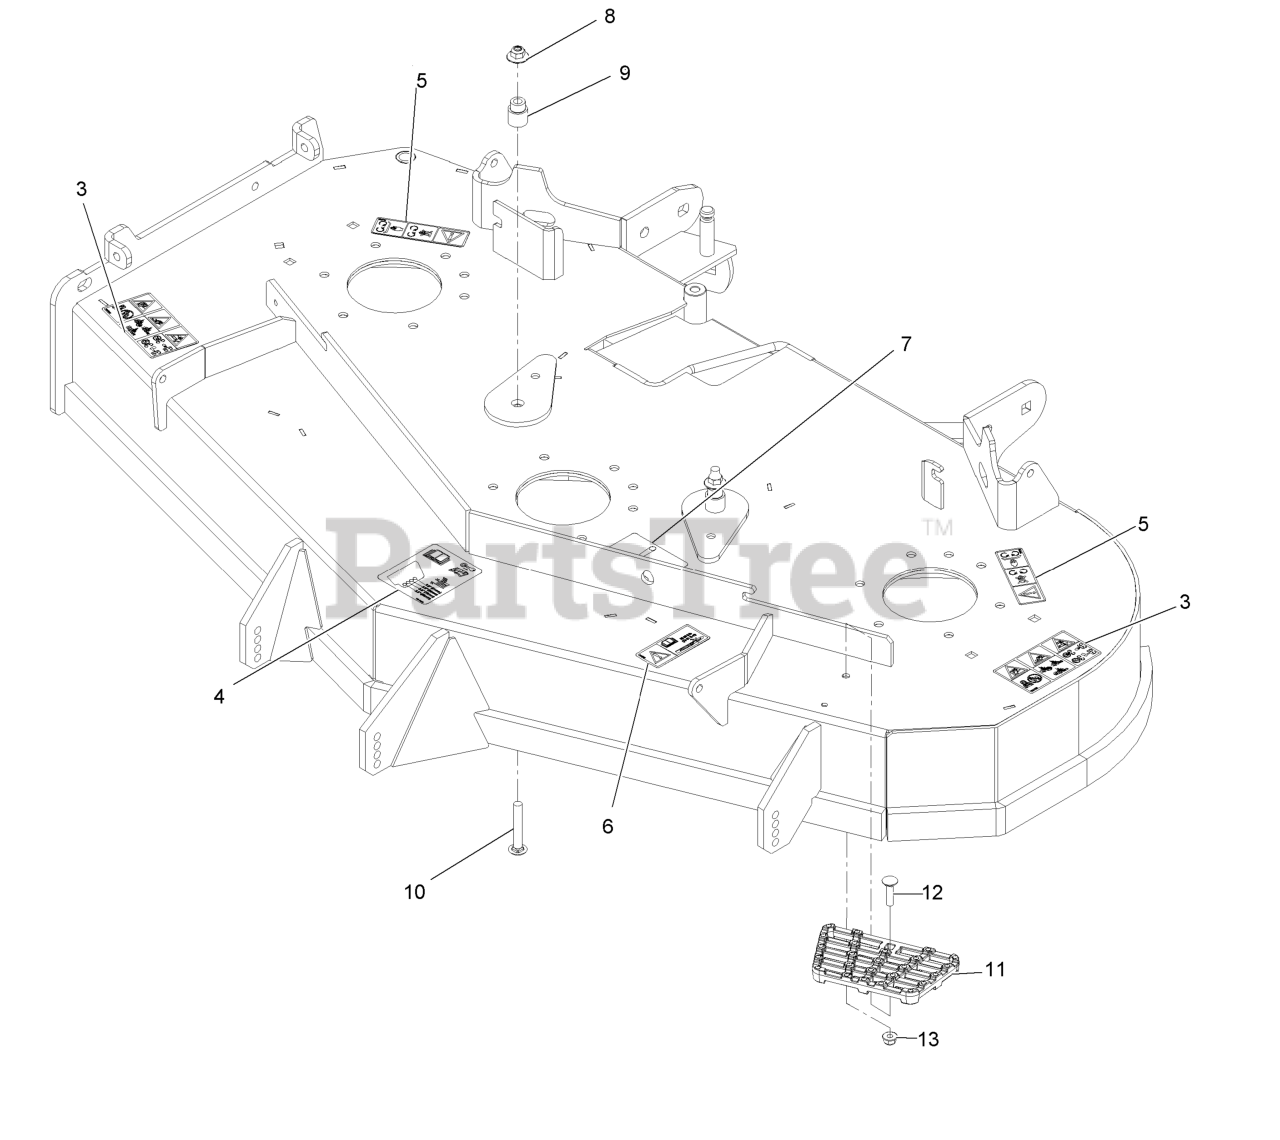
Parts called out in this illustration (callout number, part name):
3	Decal-Danger Thrown Objects
4	Decal-Roller, Anti-Scalp
5	Decal-Cover, Missing
6	Decal-Bolt Torque
7	Decal-Belt Routing
8	Nut-Nyloc 3/8-16 Flg
9	Bushing, Idler
10	Bolt-Carriage 3/8-16 X 2 1/2
11	Step-Deck
12	Bolt-Carriage 5/16-18 X 1 1/4
13	Nut-Nyloc 5/16-18 Flg
